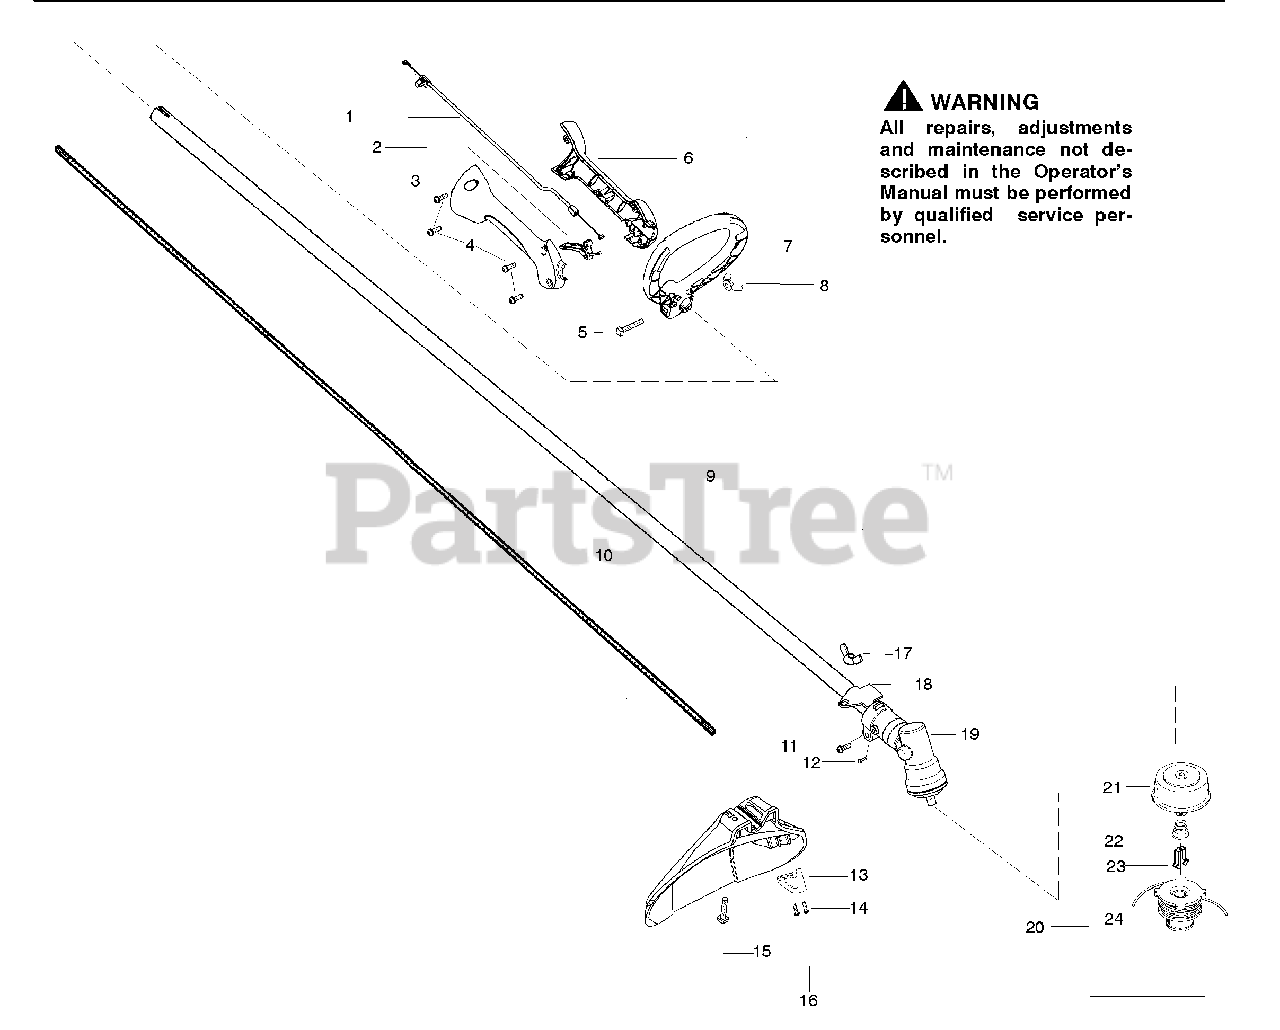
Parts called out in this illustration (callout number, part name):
1	Assy-Throttle Cable
3	Throttle Hsg.
4	Screw-Throttle Hsg.
5	Bolt-Handle/Shield
6	Throttle Hsg.
7	Handle-Assist
8	Wingnut
9	Assy-Drive Shaft Hsg.
10	Shaft-Flex
12	Screw-Alignment
13	Line Limiter
14	Screw-Line Limiter
16	Kit-Shield Assy
17	Wingnut
18	Bracket-Shield
19	Assy-Gearbox
20	Accy-TNG VI Cutting Head
21	Assy-Hub
22	Spring-Compression
23	Clip-Retainer-Head
24	Accy- Spool w/Line
